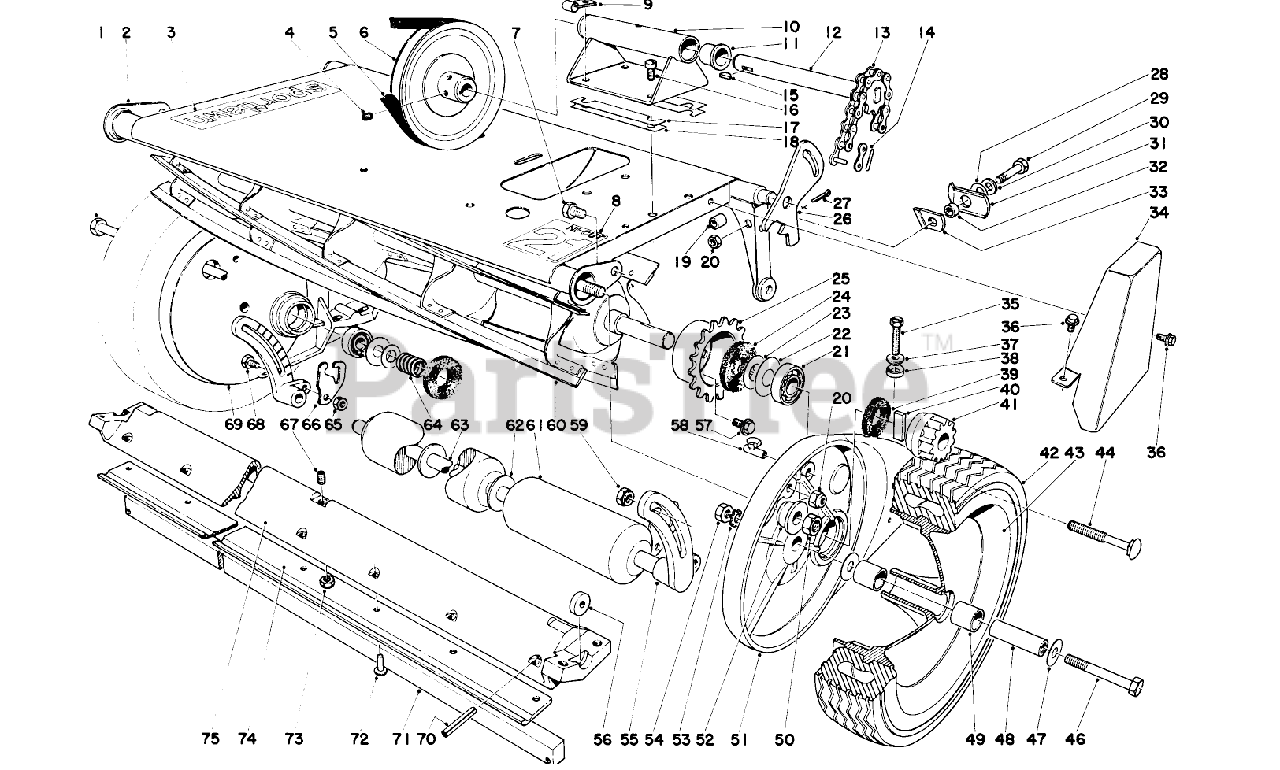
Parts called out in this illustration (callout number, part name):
1	Tie Rod
2	Platform W.A.
3	Decal
4	SCREW-SET, HSH
7	SCREW-HH
8	Decal 21" (Hi-Cut)
8	Decal 18"
9	R-CLAMP
11	BUSHING
13	ROLLER DRIVE CHAIN
15	KEY-WOODRUFF
20	NUT-LOCK, INSERT
21	BALL BRG
25	Sprocket
27	PIN-COTTER
29	Screw
30	WASHER-PLAIN
36	SCREW-HH
38	L SPHER WASHER
39	FELT WASHER
47	WASHER
49	BUSHING
51	Side Plate Assy., L.H. (Incl. Items 61 64)
53	WASHER-LOCK/EXT
54	NUT-JAM
58	Oiler
61	ROLLER
62	WASHER-FLAT
63	ROLLER SHAFT
66	GRASS CATCHER HOOK
67	SCREW-SET, HSH
68	SCREW-HH
70	PIN-ROLL
